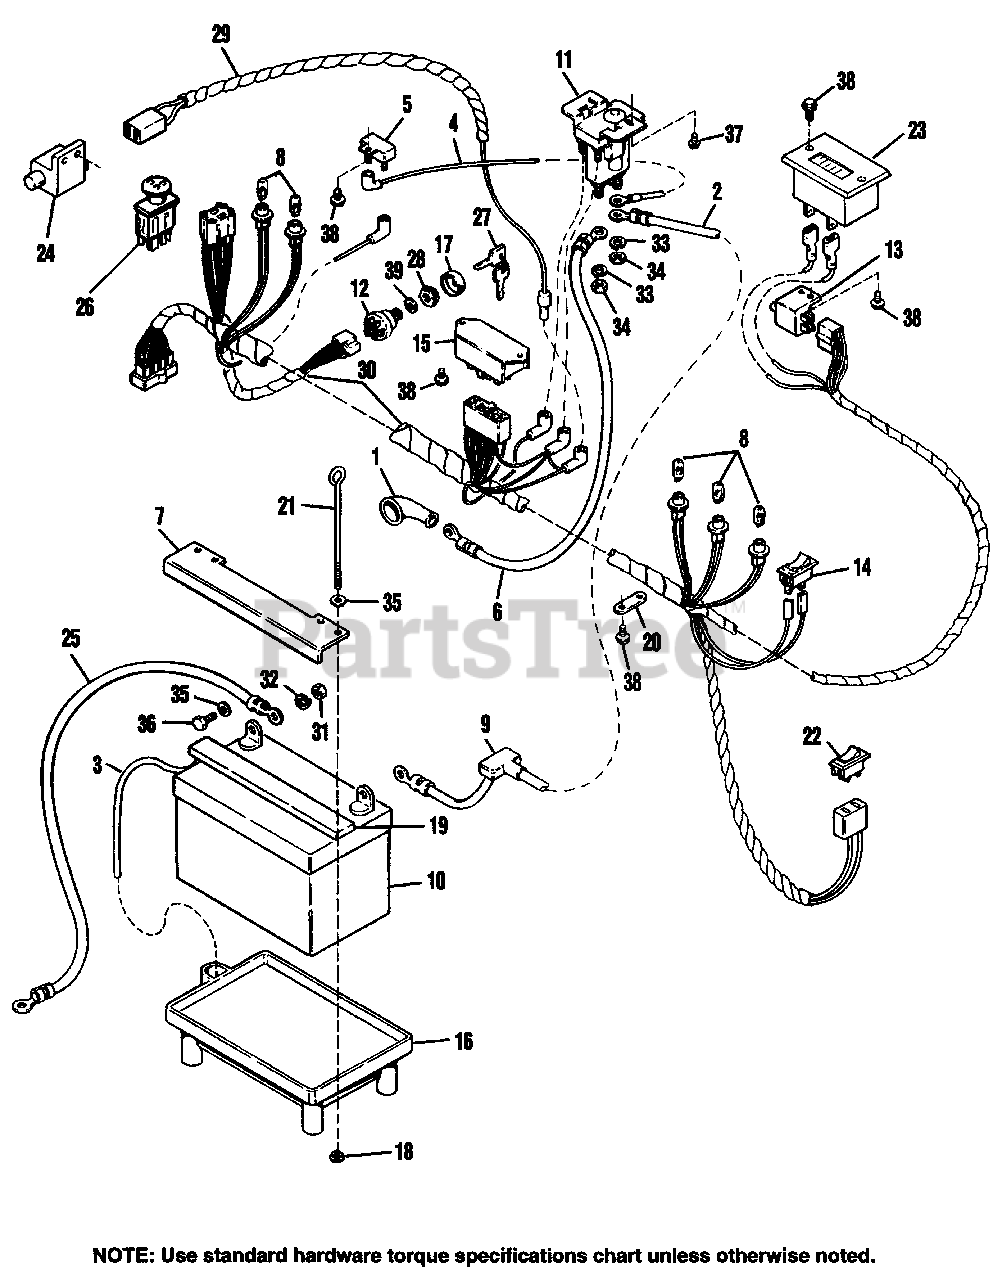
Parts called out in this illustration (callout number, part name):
1	COVER, Terminal
2	CABLE, Battery-to-Solenoid
3	HOSE, Battery, Drain
5	CIRCUIT BREAKER
6	CABLE, Solenoid-to-Starter
7	HOLD DOWN, Battery
8	BULB, Indicator Light
9	BOOT, Insulator
10	BATTERY, 39 Amp (Power Max)
11	SOLENOID
12	IGNITION SWITCH (Incl. Ref. No. 27, 28, 39)
13	SWITCH, Transmission, Neutral Start
14	SWITCH, Headlight
16	TRAY, Battery
17	COVER, Key Switch
18	NUT, Plastic, 1/4-20
19	VENT, Battery
20	STRAP, Wire Retainer
21	ROD, Battery Hold Down
22	SWITCH, Lift
24	SWITCH
25	CABLE, Battery-to-Ground
26	SWITCH, PTO, Electric Clutch
27	KEY, Ignition
28	ADAPTER, Nut
29	HARNESS, Wiring
30	HARNESS, Upper
31	NUT, Hex, Full, 1/4-20
32	LOCKWASHER, 1/4
33	LOCKWASHER, 5/16
34	NUT, Hex, 5/16-24
35	WASHER, Plain, 9/32
36	CAPSCREW, Hex, 1/4-20 x 3/4
37	SCREW, Plastite, 1/4-20 x 5/8
38	SCREW, Plastite, #8-16 x 1/2
39	LOCKWASHER, Internal Tooth
